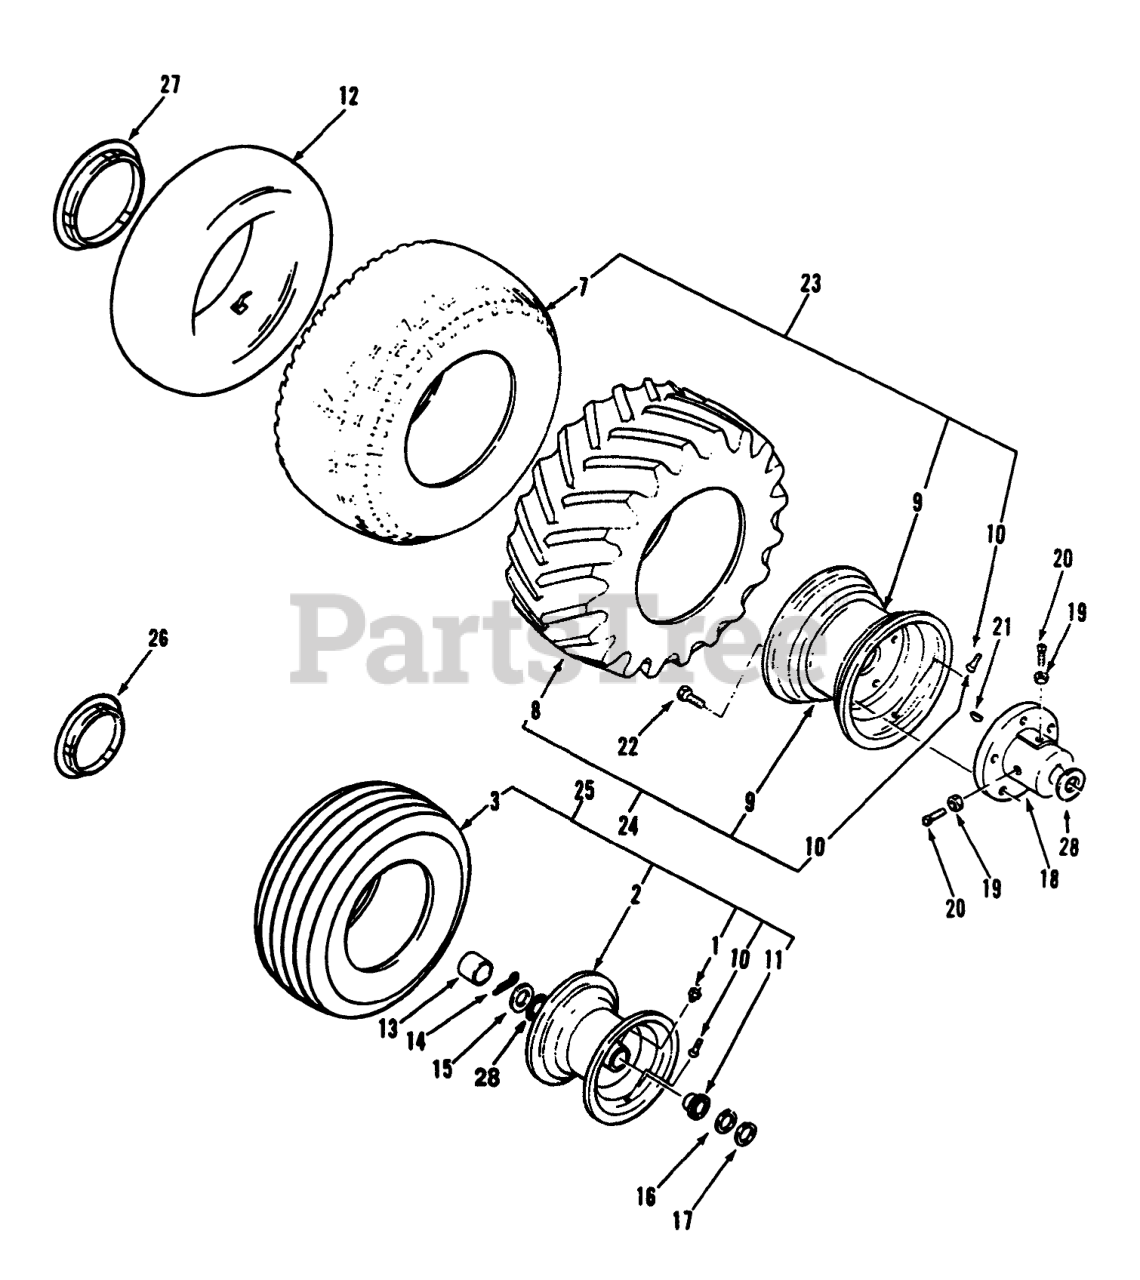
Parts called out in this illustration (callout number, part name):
1	ZERK-GREASE
2	Rim-Front
3	Tire (16 x 6.5-8) 2-Ply -2 Wheel Axel
7	TIRE
8	Tire-Cleat, Rear
9	WHEEL
10	VALVE
11	BEARING-WHEEL
12	TUBE-INNER
13	HUBCAP
14	PIN-COTTER
15	WASHER WHEEL
16	WASHER
17	WASHER-SHIM
18	Hub Rear
19	NUT-JAM
20	SCREW-SET, SQH
21	KEY-WOODRUFF
22	Lug Nut
23	ASM-Wheel& Tire
24	ASSY WHEEL & TIRE
25	Tire Assy-Front Wheel
26	8"-HUB CAP LOGO
27	12"-HUB CAP LOGO
28	WASHER-THRUST
